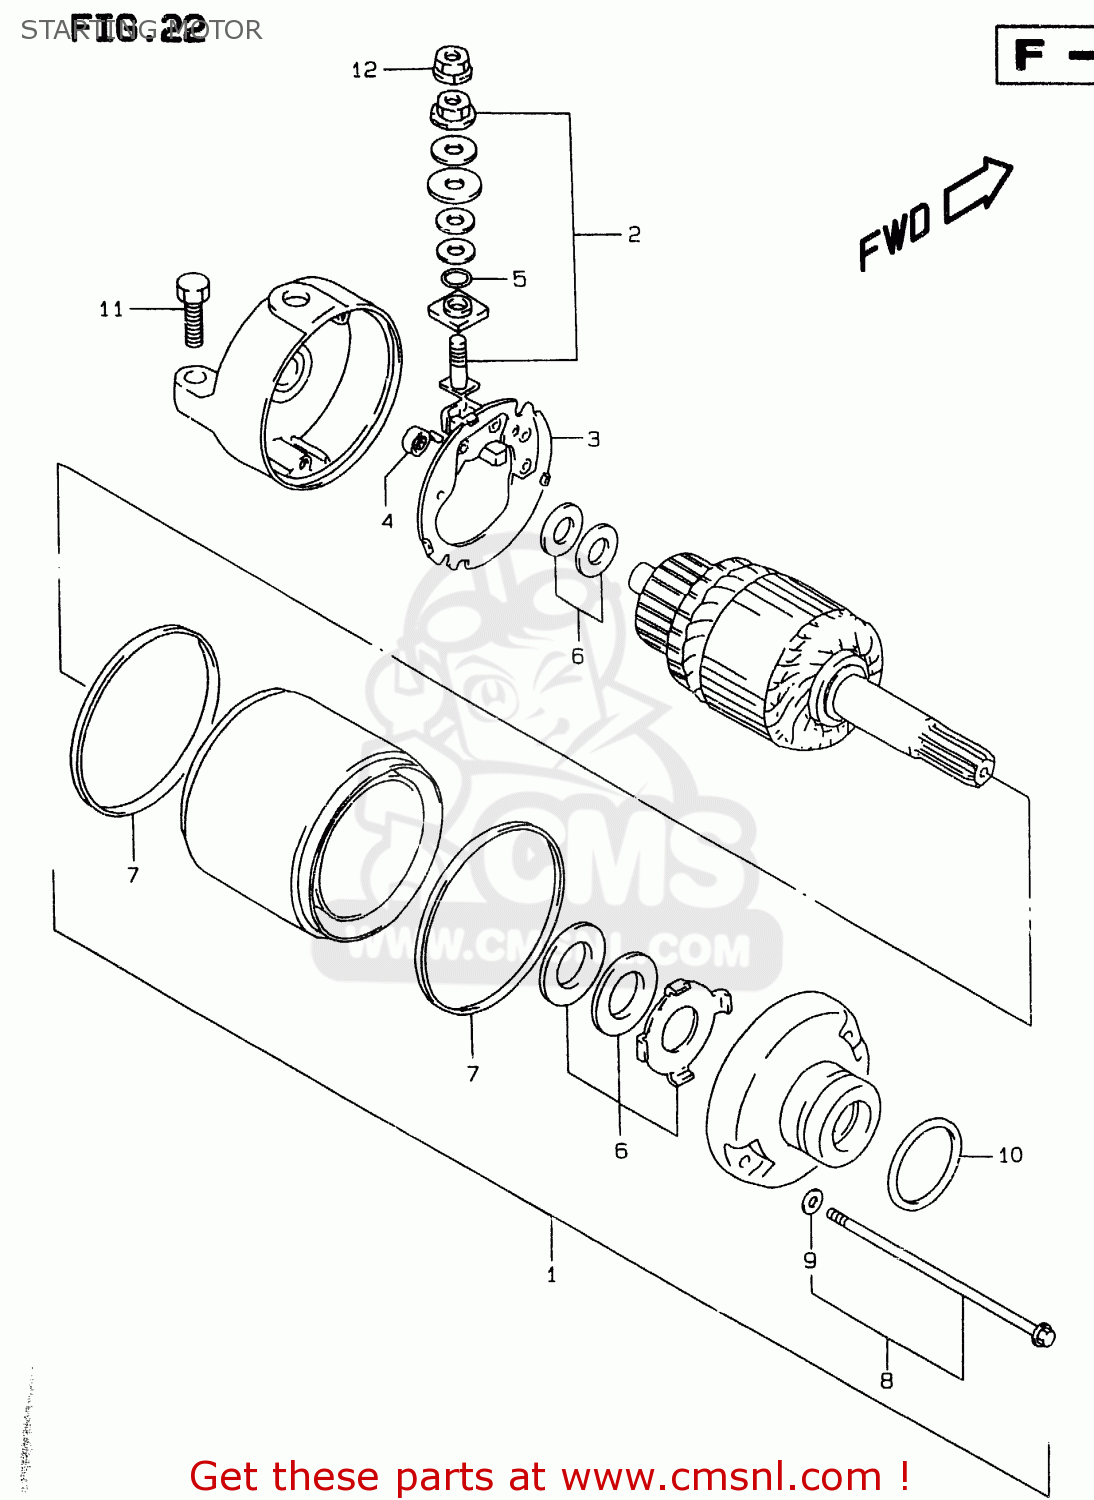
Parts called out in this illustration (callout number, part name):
1	MOTOR ASSEMBLY,STARTING
2	BRUSH TERMINAL SET
3	BRUSH HOLDER SET
4	SPRING,BRUSH
5	O RING
6	SHIM SET,STARTING MOTOR
7	O RING
8	BOLT
9	O RING
10	O RING(D:3,ID:24.5)
11	SCREW (6X25)
12	NUT
